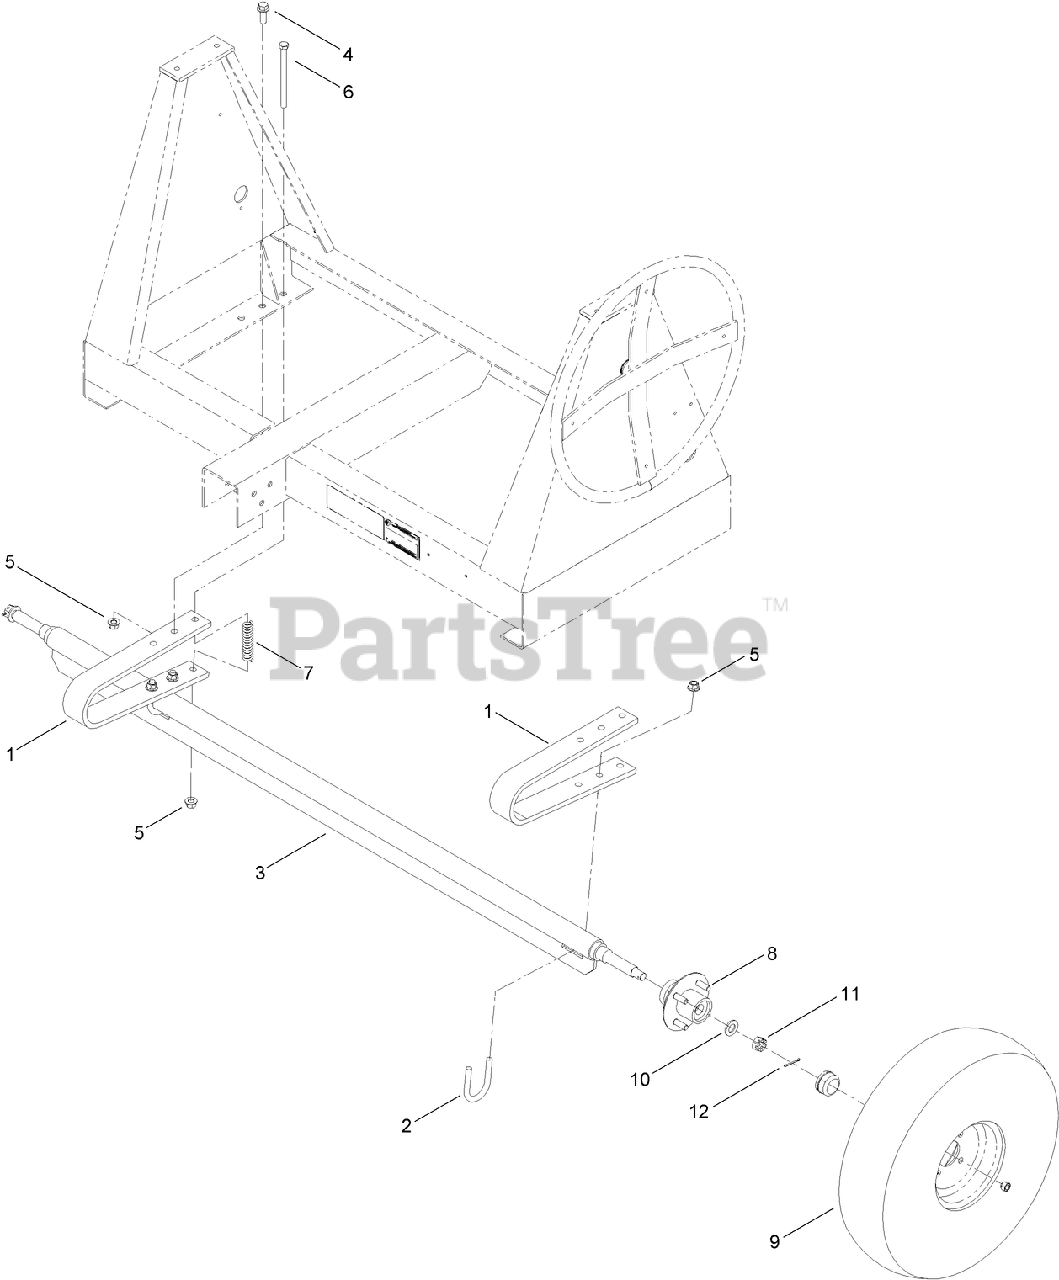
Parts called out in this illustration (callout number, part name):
1	SPRING-LEAF
2	BOLT-U
3	AXLE-SPRING
4	SCREW-HHF
5	NUT-LOCK
6	SCREW-HH
7	SPRING-COIL
8	HUB ASM
9	TIRE AND RIM ASM
10	WASHER-FLAT
12	PIN-COTTER
